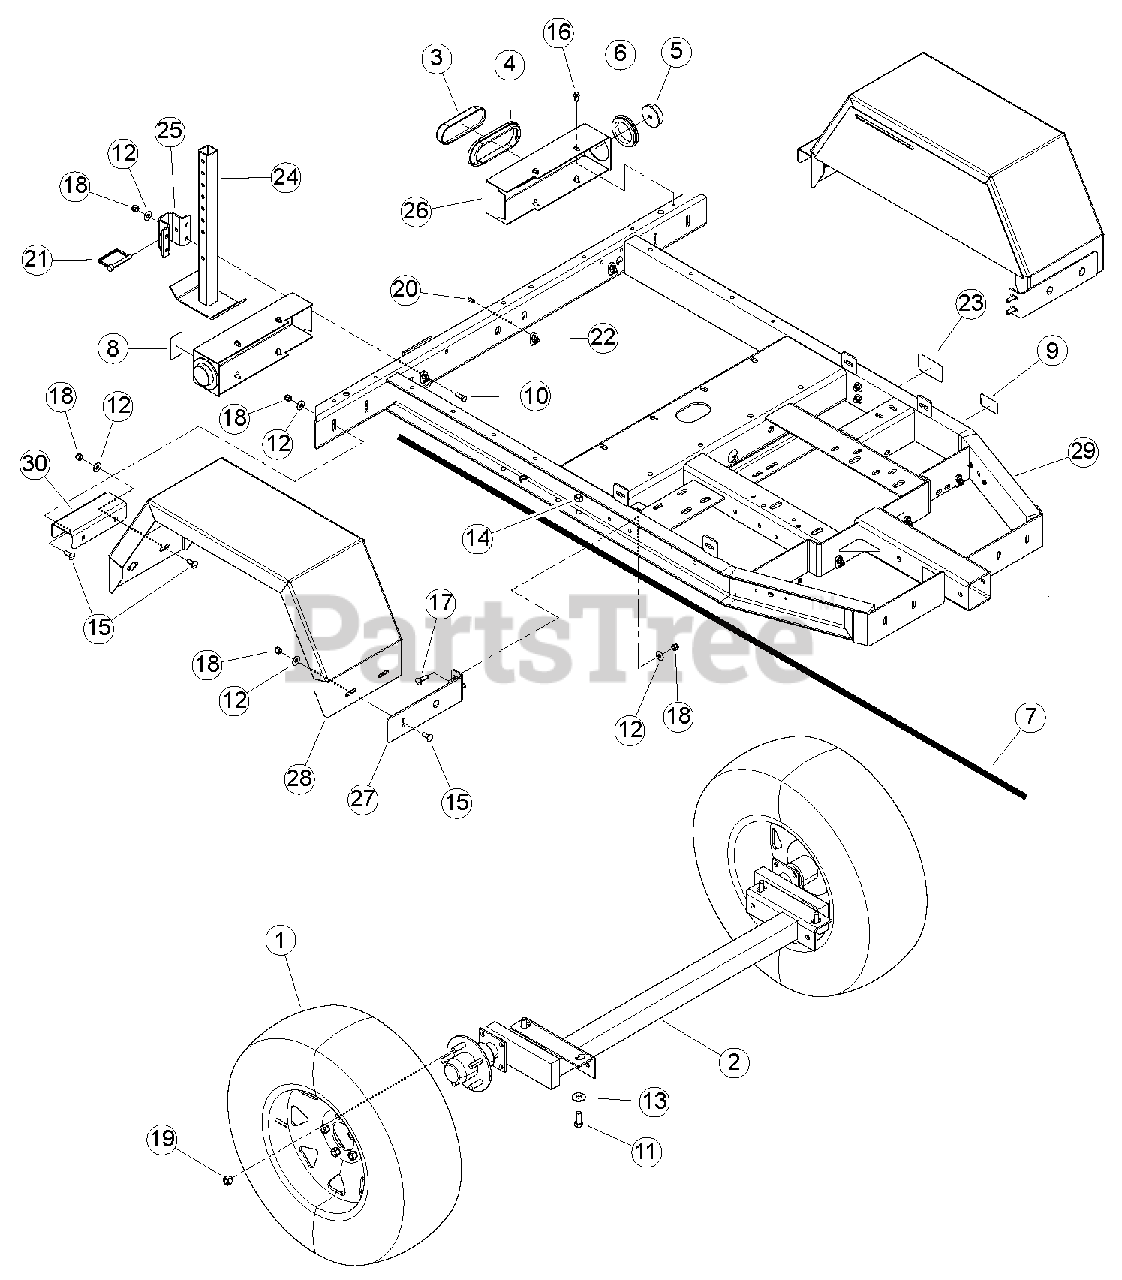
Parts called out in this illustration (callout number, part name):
1	ASSY, 15 INCH TIRE + WHEEL
2	AXLE, 2500 LB TORSION
3	TAIL LIGHT, OVAL RED
4	GROMMET, OVAL TAIL LIGHT
5	LIGHT, RED CLEARANCE
6	GROMMET, CLEARANCE LIGHT
7	WIRE HARNESS, TRAILER
8	REFLECTOR, WIDE ANGLE RED
9	REFLECTOR, WIDE ANGLE AMBER
10	BOLT, 3/8 X 1 HEX HD GR5 ZP
11	BOLT, 1/2 X 1-1/4 HEX HD GR5 NC ZP
12	WASHER, 3/8 FLAT ZP
13	WASHER, 1/2 FLAT ZP
14	NUT, 1/2 CENTERLOCK GRB ZP
15	BOLT, 3/8 X 1 CRG GR5 NC ZP
16	SCREW, 11/32 X 7/8 HWH AB THREAD ZP
17	BOLT, 3/8 X 1-1/4 CRG GR5 NC ZP
18	NUT, 3/8 NE NYLOCK ZP
19	NUT, 1/2-20 WHEEL
20	RIVET, AL BLIND 1/4 X 3/4 DOME HEAD
21	PIN, 3/8" X 2-3/4" SNAP
22	CLAMP, CABLE MOUNT
23	DECAL, P215/70R15 LOAD RATING
24	WELDMENT, REAR STABILIZER
25	GUIDE, TRAILER SUPPORT
26	BRACKET, TAILLIGHT
27	BRACKET, FENDER
28	WELDMENT, CHIPPER FENDER
29	WELDMENT, CHIPPER TRAILER
30	PLATE, FENDER SPACER
